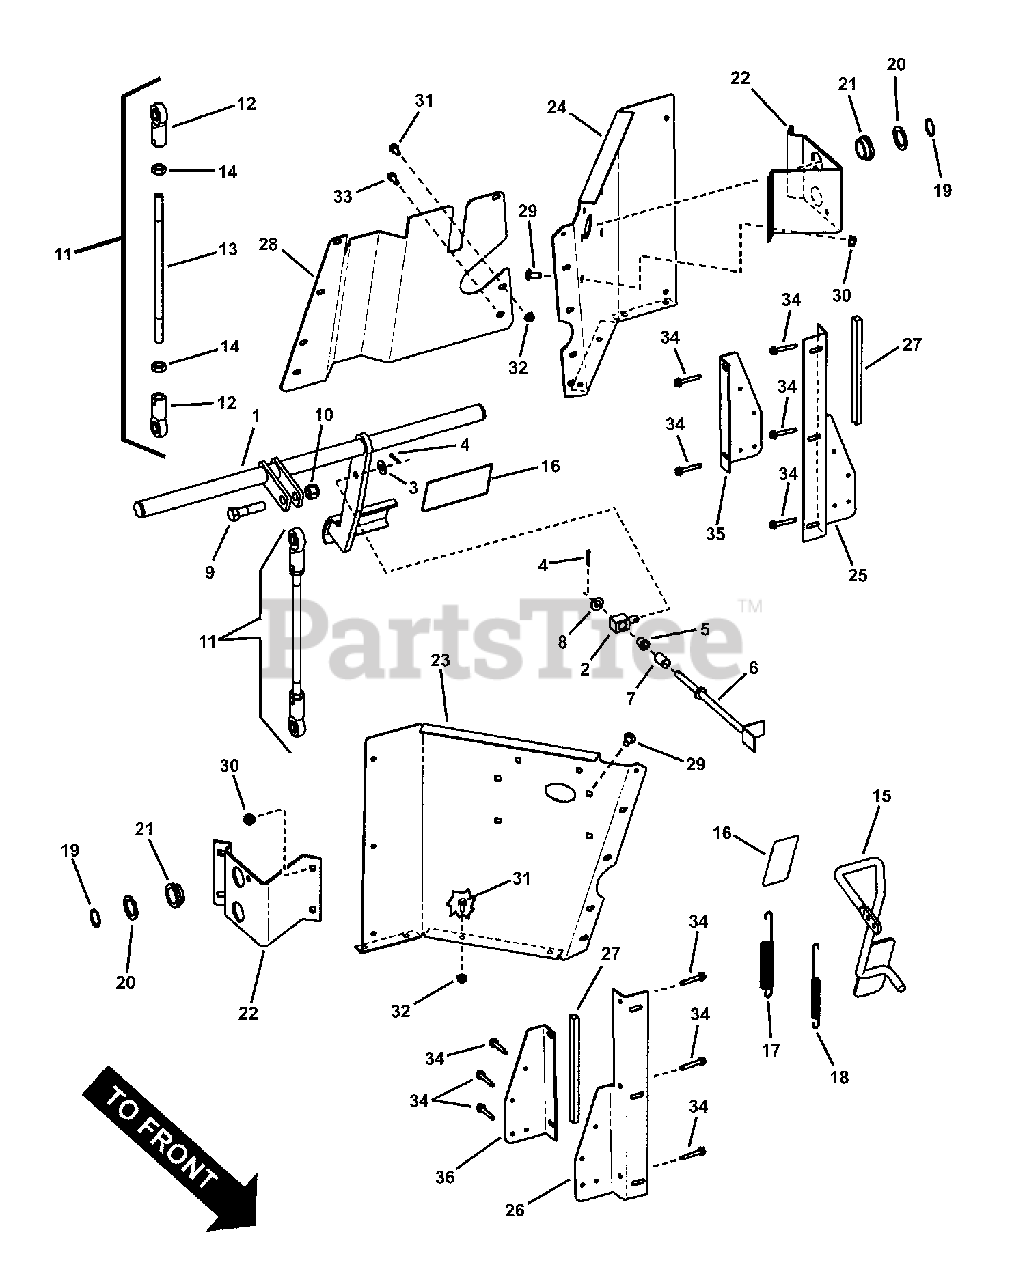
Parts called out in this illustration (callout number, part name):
1	WELDMENT, CVT Brake Pedal
2	SWIVEL, Brake Rod
3	WASHER, .375 x .875 x .083 Flat
4	COTTER PIN, 1/8 x 3/4"
5	FLANGE BUSHING, .381 x .625 x .62
6	WELDMENT, Brake Switch Rod
7	SPRING
8	WASHER, 3/8" SAE Flat
9	SCREW, 1/2-13 x 2" Hex Head Cap, GR 5
10	NUT, 1/2-13 Hex Nyloc
11	ASSEMBLY, Upper Brake Rod
12	ROD END, Female 1/2-20 thread
13	ROD, Upper CVT Brake (1/2-20 thread)
14	NUT, 1/2-20 Hex Jam, GR 5 or B
15	WELDMENT, Throttle Pedal
16	PEDAL GRIP
17	SPRING, Throttle Pedal Return
18	SPRING, Inner Throttle Return
19	RING, 1.00 Dia. External Retaining
20	BUSHING, 14 Gage Machine
21	BEARING, 1" I.D.
22	BRACKET, Brake Support (Red)
22	BRACKET, Brake Support (Green)
23	FIREWALL, LH (Red)
23	FIREWALL, LH (Green)
24	FIREWALL, RH (Red)
24	FIREWALL, RH (Green)
25	FILLER, Firewall LH (Red)
25	FILLER, Firewall LH (Green)
26	FILLER, Firewall RH (Red)
26	FILLER, Firewall RH (Green)
27	GASKET, Closed Cell, Adhesive Back
28	PEDAL SHIELD (Red)
28	PEDAL SHIELD (Green)
29	BOLT, 5/16-18 x 3/4" Short Square Neck Carriage, GR 5
30	NUT, 5/16-18 Hex Flange Lock, GR 5
31	SCREW, 1/4-20 x 1/2" Hex Flange Lock, GR 5
32	NUT, 1/4-20 Hex Flange Lock, GR 5
33	SCREW, 1/4-20 x 5/8" Hex Washer Self-Tap
34	SCREW, #10-16 x 1-1/4" Truss Head Sheet Metal
35	* KICK PLATE, LH
36	* KICK PLATE, RH
